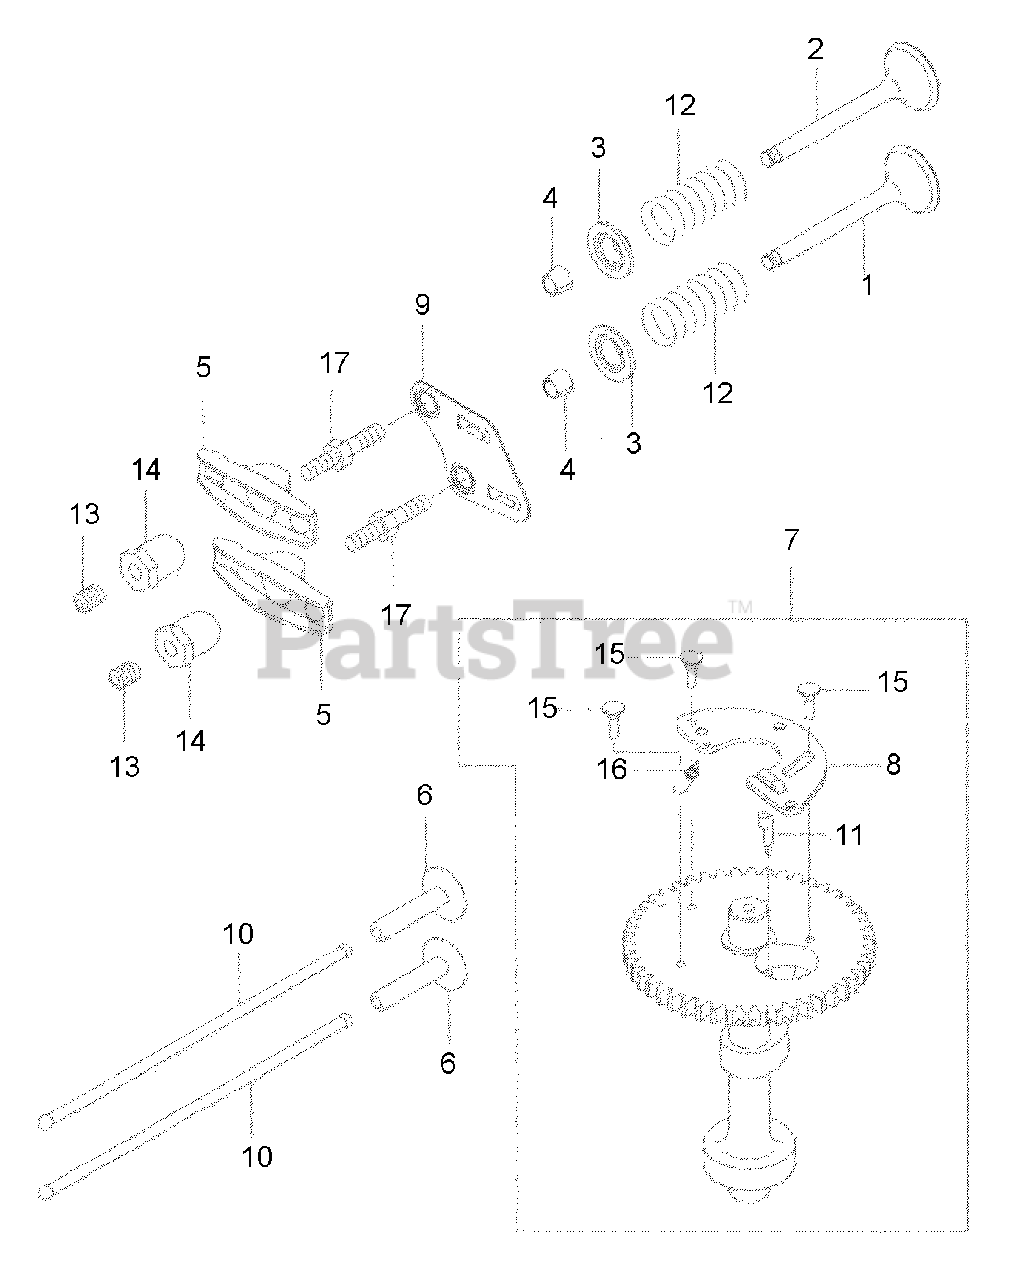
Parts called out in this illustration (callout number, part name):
1	Intake Valve
2	Exhaust Valve
3	Valve Spring Retainer
5	Rocker Arm
7	Camshaft Assy.
10	Push Rod
17	Bolt
